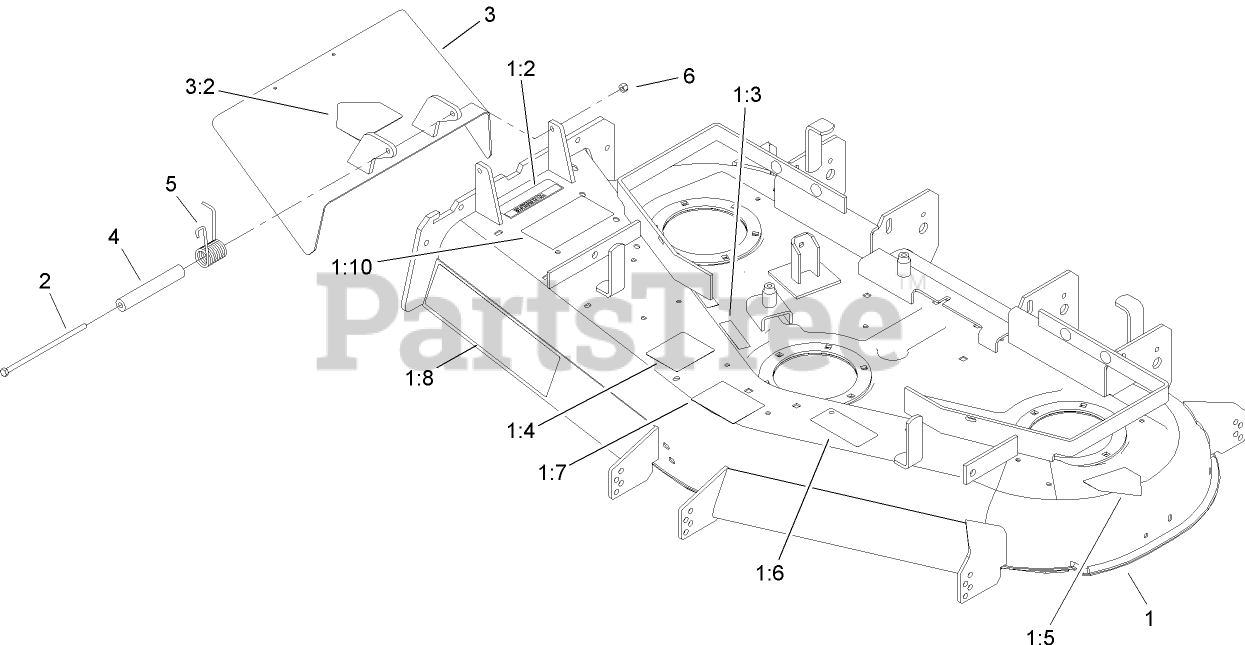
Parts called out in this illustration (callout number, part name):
1	DECK ASM
1:2	DECAL-WARNING
1:3	DECAL-COVER, MISSING
1:4	DECAL-ROUTING, BELT
1:5	DECAL-DANGER
1:6	DECAL-TORQUE, BLADE BOLT
1:7	DECAL-WHEEL, GAGE
1:8	DECAL
1:10	DECAL-DANGER, THROWN OBJECT
2	SCREW-HH
3	Deflector ASM
3:2	DECAL-DANGER
4	SPACER
5	SPRING-TORSION
6	NUT-LOCK, NI
